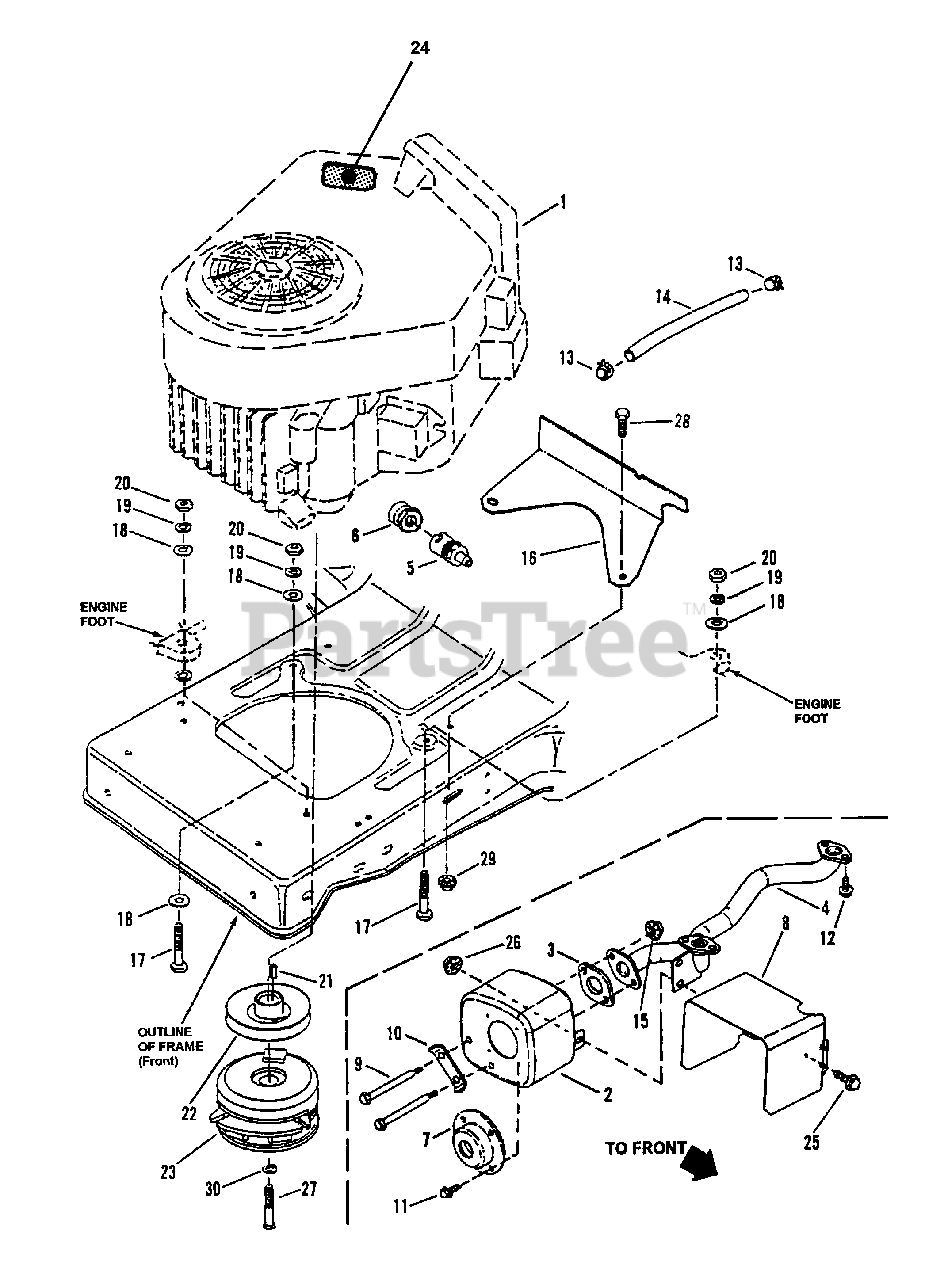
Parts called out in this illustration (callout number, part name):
2	MUFFLER
3	GASKET, Muffler/Exhaust
4	MANIFOLD, Exhaust
5	ASSEMBLY, Oil Valve Drain
6	EXTENSION, Oil Drain
7	DEFLECTOR, Exhaust
8	SHIELD, Muffler Heat
9	BOLT, 5/16-18 x 3-1/2" Shoulder, Hex Head
10	LOCK, Screw
11	SCREW, #8-18 x 1/2" Self-Tapping
12	SCREW, 5/16-18 x 1/2" Hex Washer Head, Self Tapping
13	CLAMP, Fuel Line
14	LINE, Fuel, 14" Long
15	NUT, 5/16-18 Hex Flanged Lock, Grade 5
16	SHIELD, Heat
17	SCREW, 5/16-18 x 1-3/4" Hex Head Cap, Grade 5
18	WASHER, 5/16 Flat Grade 5
19	WASHER, 5/16 Split Lock
20	NUT, 5/16-18 Hex Grade 5 or B
21	KEY, 1/4 x 1/4 x 3/4" Square
22	PULLEY, Traction Drive
23	CLUTCH/BRAKE
24	DECAL, Warning Speed Setting
25	SCREW, 1/4-20 x 5/8" Hex Head Cap, Grade 5
26	NUT, 1/4 -20 Hex Flanged Lock, Grade 5
27	SCREW, 7/16-20 x 2-1/2 Hex Head Cap, Special, Grade 5
28	SCREW, 5/16-18 x 1" Hex Head Cap, Grade 2
29	NUT, 5/16-18 Hex Flange Lock, Grade 5
30	WASHER, 7/16 Split Lock
